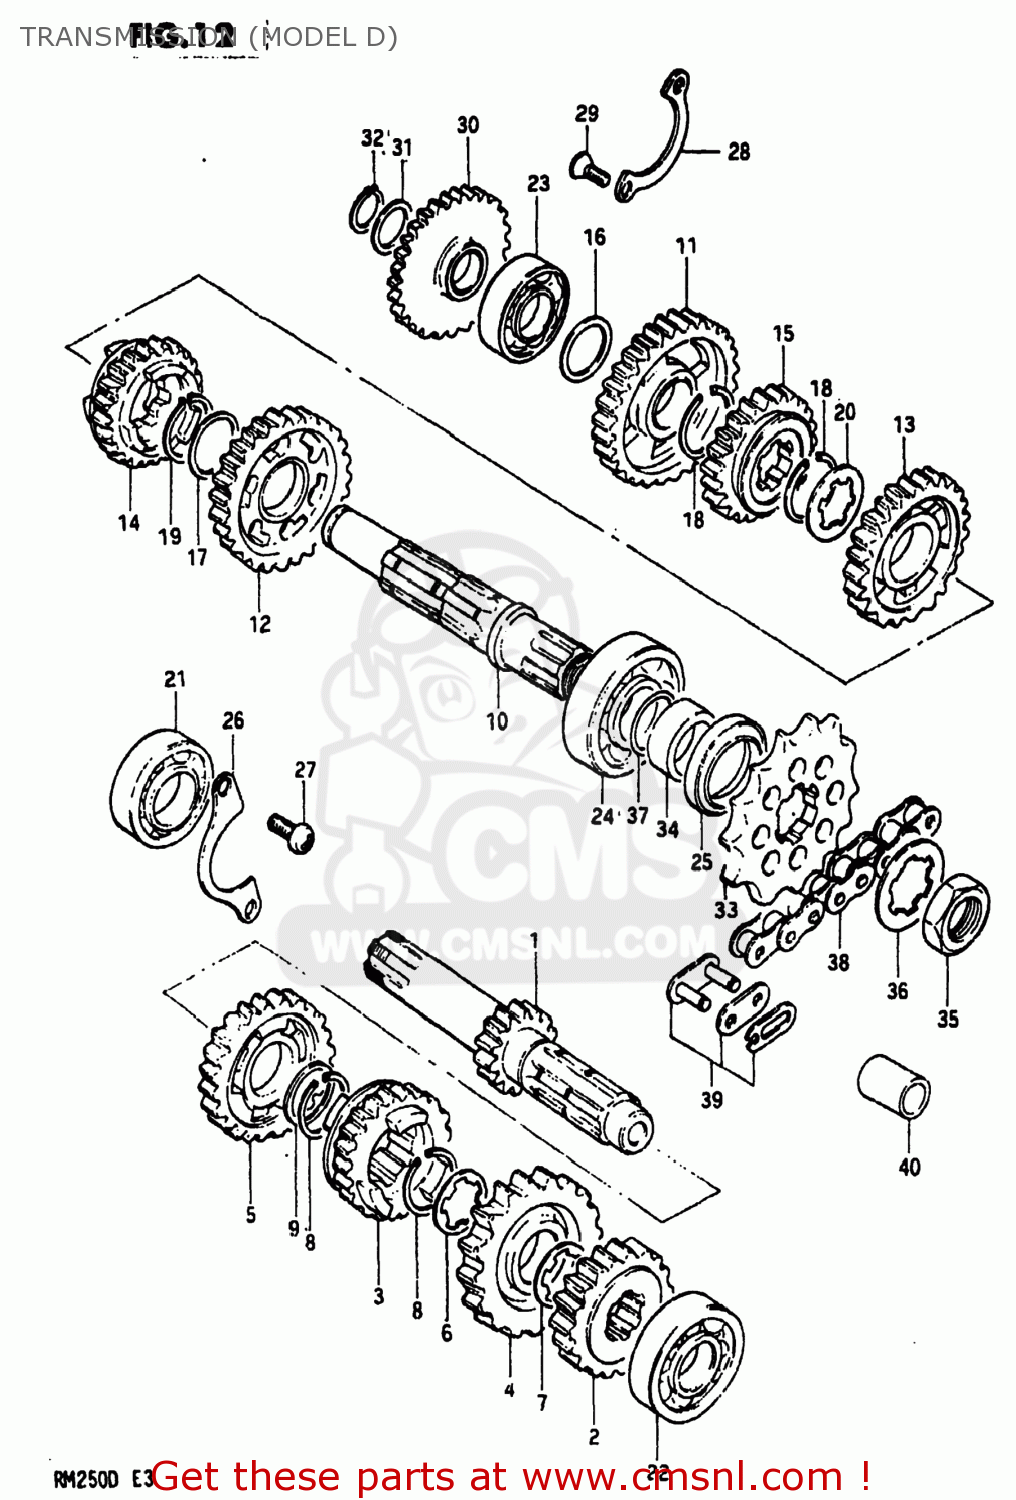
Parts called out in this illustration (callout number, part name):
1	SHAFT,COUNTER
2	GEAR,SECOND DRIVE
3	GEAR,THIRD DRIVE
4	GEAR,FOURTH DRIVE
5	GEAR,FIFTH DRIVE
6	WASHER,LOCK
7	WASHER,LOCK
8	CIRCLIP
9	SHIM(22X28X0.5)
10	SHAFT,DRIVE
11	GEAR,FIRST DRIVEN
12	GEAR,SECOND DRIVEN
13	GEAR,THIRD DRIVEN
14	GEAR,FOURTH DRIVEN
15	GEAR,FIFTH DRIVEN
16	WASHER
17	SHIM
18	CIRCLIP
19	CIRCLIP,25MM
20	WASHER,LOCK
21	BEARING
22	BEARING
23	BEARING
24	BEARING
25	SEAL,OIL(32X42X6)
26	PLATE,COUNTERSHAFT BEARING
27	SCREW 6X12
28	PLATE,DRIVESHAFT BEARING
29	SCREW
30	GEAR,KICK STARTER IDLE
31	WASHER
32	CIRCLIP
33	SPROCKET,ENGINE
34	SPACER(22X32X9.5)
35	NUT
36	WASHER,LOCK
37	O RING(D:1.7,ID:22)
38	CHAIN ASSEMBLY,DRIVE
39	JOINT ASSEMBLY,CHAIN
40	SPACER(12X20X15.3)
